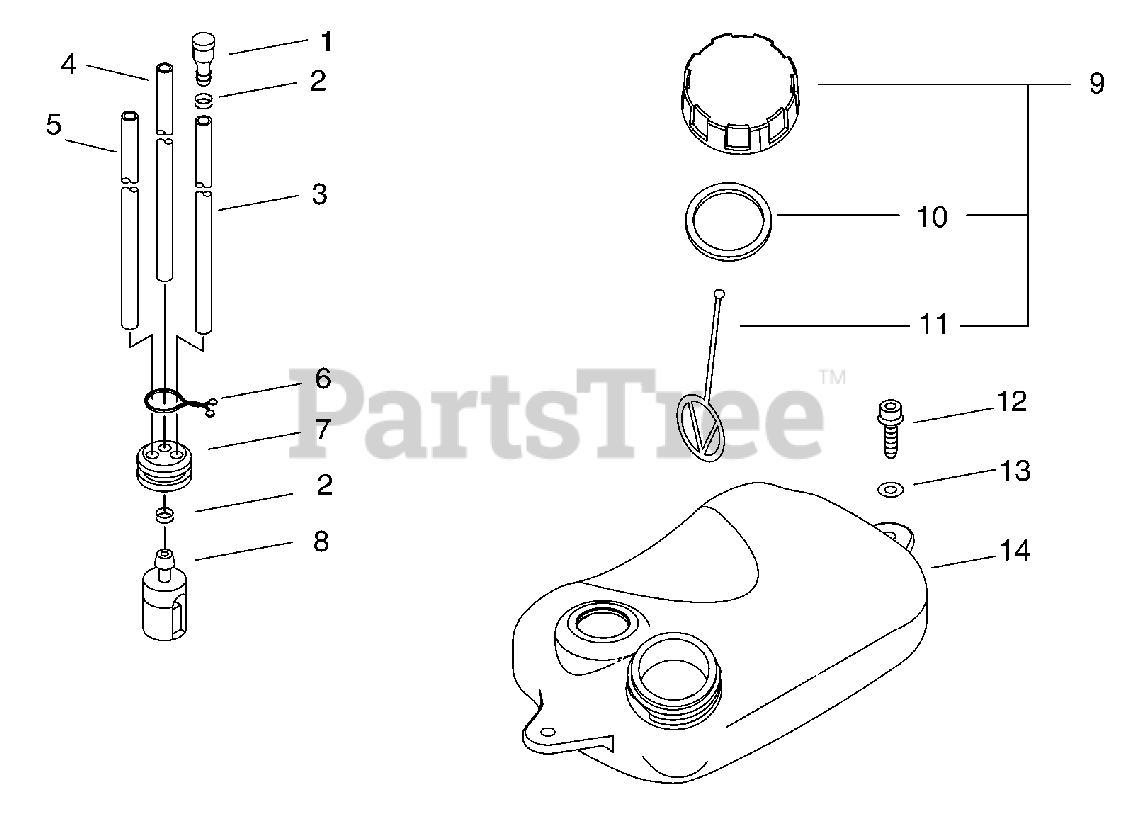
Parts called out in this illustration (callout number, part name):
1	VENT ASSY
2	CLIP Ø6
3	PIPE, FUEL 3x-5x-70 BLACK
4	PIPE, FUEL 3×5×210 BLACK
5	PIPE, FUEL 3×6×125
6	CLIP, TUBE
7	GROMMET, FUEL
8	FILTER, FUEL
9	CAP ASSY, FUEL
10	GASKET, FUEL CAP
11	CONNECTOR, CAP L= 100 MM
12	BOLT 5×20
13	WASHER 5.5×16×2T
14	TANK, FUEL
